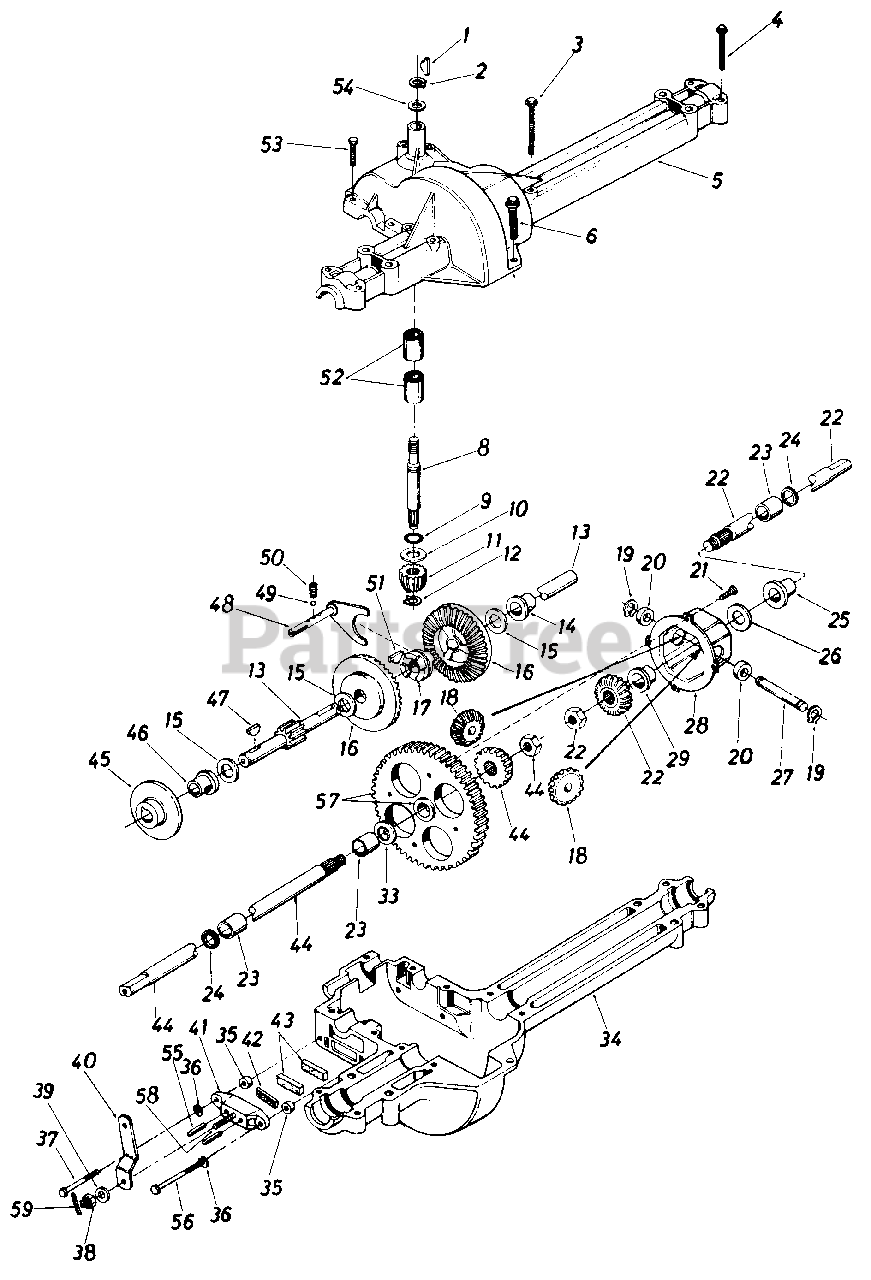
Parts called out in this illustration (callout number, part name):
1	#4 Hi-Pro Key 3/32 x 518" Dia.
2	Snap Ring .625" Shaft
3	Hex Wash. TT-Tap Scr. 1/4-20 x 1.75" Lg .
4	Hex Bolt 5/16-18 x 2.5"
5	Upper Housing
6	Hex Fl-Bolt 1/4-20 x .88" Lg.
9	Square Seal 5/8" I.D.
10	Thrust Washer 5/8" I.D. x 1.25" O.D.
11	Pinion Input 14T
12	Retaining Ring 7/16" Ext.
14	Flange Brg. 5/8" I.D. x 3/4"
15	Fl-Wash. 5/8" I.D. x 1.0" O.D. x .020" Thk.
16	Bevel Gear 42T
17	Clutch Collar
18	Miter Gear 15T
19	Retainer Ring
20	Thrust Bearing
21	Pan Head Scr. 1/4-20 x .50" Lg. w/Patch
22	Axle R.H. Ass'y.-Kit
23	Sleeve Bearing 3/4" I.D. x 1.0" Lg.
24	Oil Seal 3/4" I.D.
25	Flange Bearing 3/4" I.D. x 15/16" Lg.
26	Fl-Wash. .760" I.D. x 1.5" O.D.
27	Cross Shaft
28	Differential Housing Ass'y.
33	Fl-Wash. .760" I.D. x 1.5" O.D.
34	Lower Housing
35	Spacer .53" O.D. x 3/8" Lg.
36	L-Wash. 1/4" I.D.
37	Hex Bolt 1/4-20 x 1.50" Lg. (Grade 5)
38	Castle Nut 5/16-24 Thd.
39	Fl-Wash. .344" I.D. x 875" O.D.
40	Actuating Arm
42	Puck Plate
43	Brake Puck
44	Axle L.H. Ass'y.-Kit
46	Flange Bearing 5/8n l.D. x 15/16" Lg.
47	Woodruff Key 3/16 x 5/8 HT
48	ShiR Fork Ass'y.
49	Ball Detent .250" Dia.
50	Spring Detent
51	#9 Hi-Pro Key 3/16" x 3/4" Dia. HT
52	Needle Brg. 5/8" I.D. x 1/2"
53	Hex Wash. TT-Tap Scr. l/4-20 x l oon Lg.
54	Fl-Wash. 5/8n l.D. x .030
55	Actuating Pin 5/16n Dia.
56	Hex Bolt 1/4-20 x 2.50" Lg. (Grade 5)
57	Differential Gear 72T Ass'y. w/Bearing
58	Sq. Hd. Bolt 5/16-24 Thd.
59	Cotter Pin 3/32n Dia. x ln Lg.
